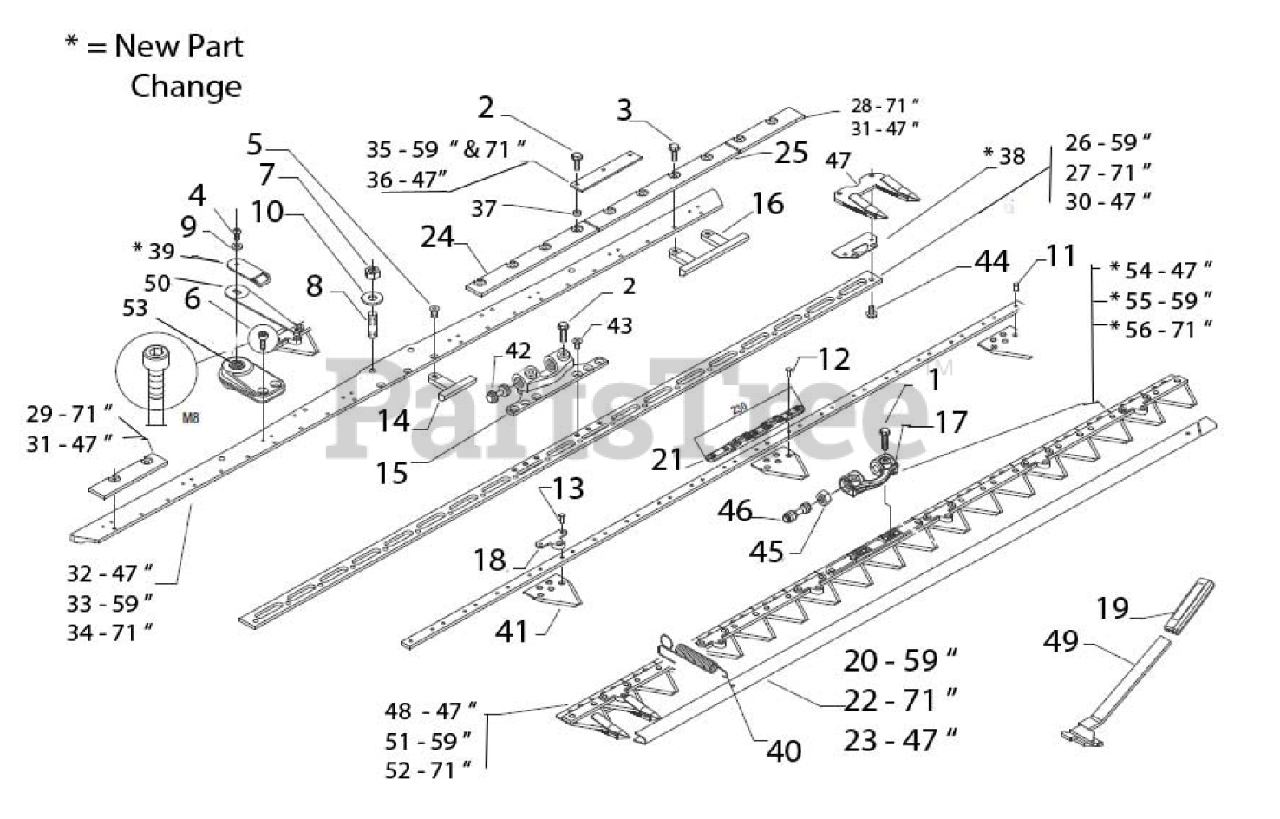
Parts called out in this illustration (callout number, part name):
1	SCREW
2	SCREW
3	SCREW
4	SCREW
5	SCREW
6	SCREW
7	NUT, M14X1 5.6S
8	STUD BOLT, M14X1.5X48X12X20
9	WASHER
10	DOME WASHER
11	RIVET, 5.3X12
12	RIVET, 5.3X14
13	RIVET, 5.3X16
14	LOWER GUIDE
15	CONNECTION
16	LOWER GUIDE
17	BLADE COUPLING
18	CONNECTION
19	KNOB
20	GUARD, BLADE 59"
21	BLADE SUPPORT
22	GUARD, BLADE 71"
23	GUARD, BLADE 47"
24	LOW BLADE GUIDE INTERNAL
25	LOW BLADE GUIDE INT. 59 & 71"
26	STRIP 59"
27	STRIP 71"
28	BLADE GUIDE 71" L
29	BLADE GUIDE 71" R
30	STRIP 47"
31	BLADE GUIDE 47" ONLY
32	CENTRAL BAR 47"
33	CENTRAL BAR 59"
34	CENTRAL BAR 71"
35	PLATE 59" & 71"
36	PLATE 47" ONLY
37	SPACER
38	SHOE
39	LIMITING BLADE HOLDER
40	SPRING
41	BLADE SECTION
42	SCREW
43	SCREW
44	SCREW
45	CONICAL NUT M16X1.5
46	SCREW FOR BLADE CONNECTION
47	TOOTH
48	BLADE ASSEMBLY 59"
49	SPRING LIFTER
50	SPRING W/ FINGER
51	BLADE ASSEMBLY 71"
52	BLADE ASSEMBLY 47"
53	SUPPORT
54	BLADE ASSEMBLY 47" W/ COUPLER & HARDWARE
55	BLADE ASSEMBLY 59" W/ COUPLER & HARDWARE
56	BLADE ASSEMBLY 71" W/ COUPLER & HARDWARE
